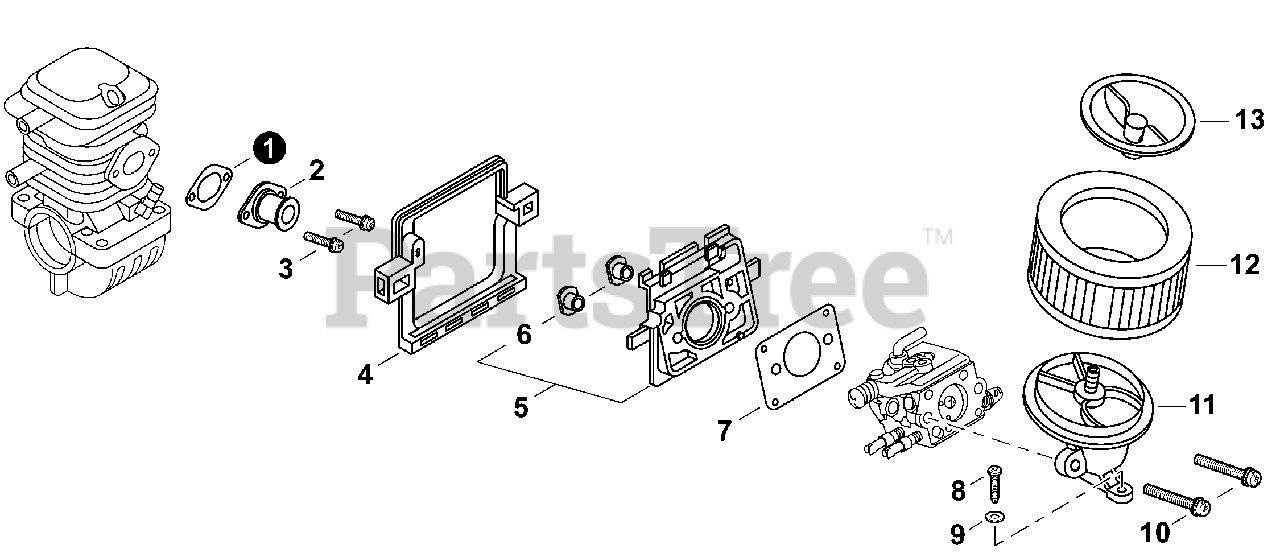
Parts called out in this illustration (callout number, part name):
1	GASKET, INTAKE
2	BELLOWS, INTAKE
3	SCREW 5×14
4	CUSHION
5	INSULATOR SET, INTAKE
7	GASKET, INTAKE
8	SCREW 5×20
9	WASHER, FLAT 5.5×10×0.8
10	SCREW 5×50
11	ADAPTOR, INTAKE
12	FILTER, HEAVY DUTY AIR
13	CAP, AIR FILTER
